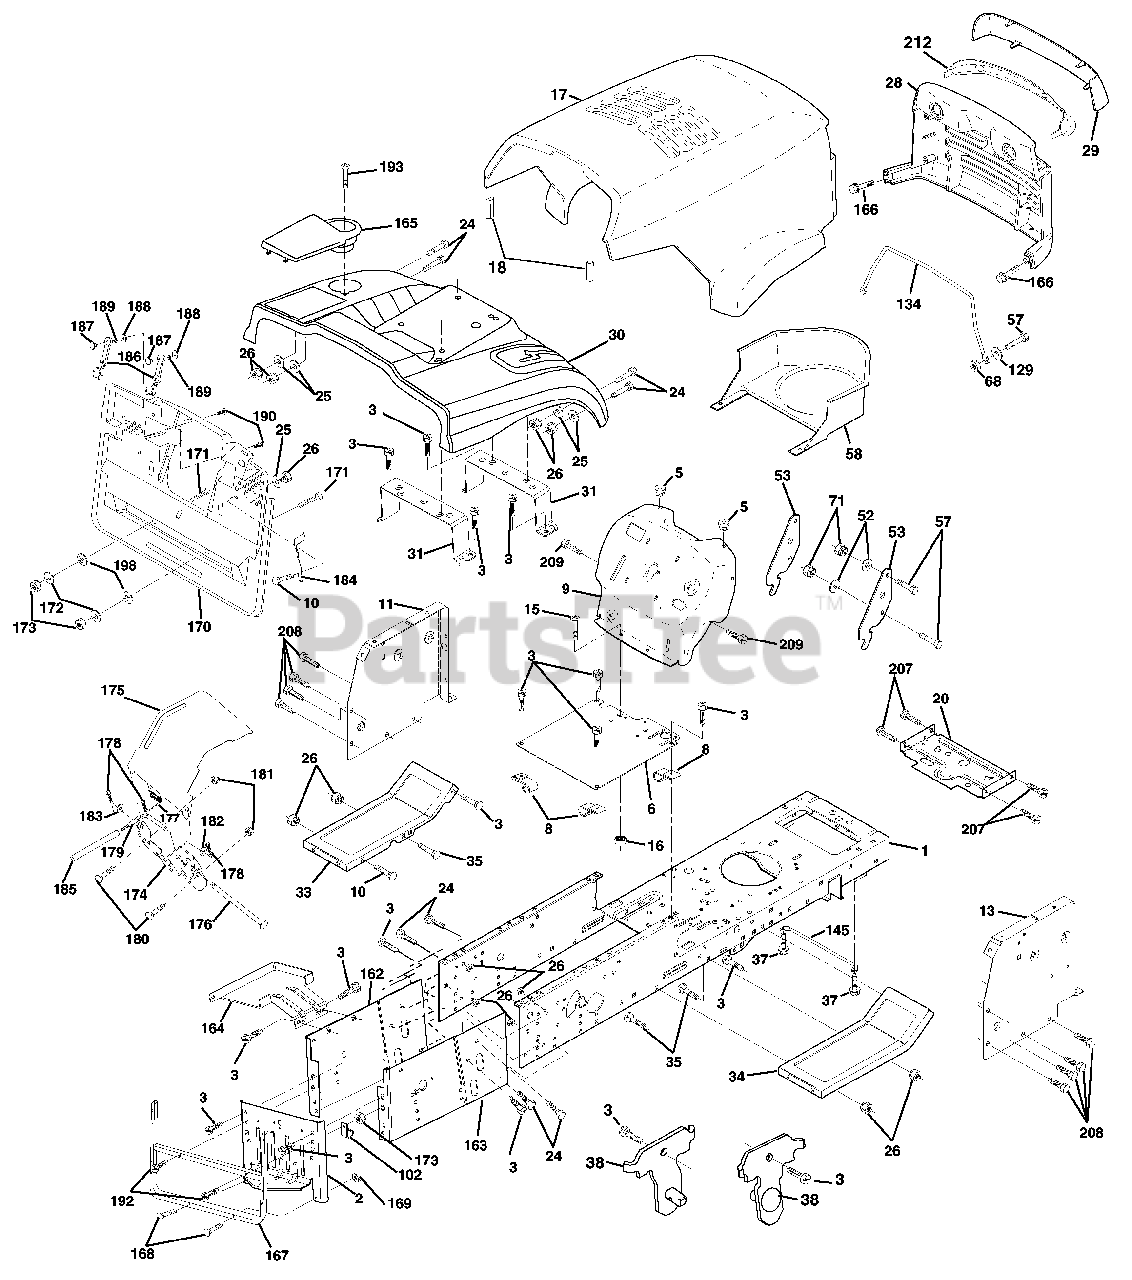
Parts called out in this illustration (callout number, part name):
1	Chassis Stamping
3	Screw 3/8-16 x 3/4
5	Bumper Hood/Dash
8	Clip Insulator 13/32 Mtg. Hole
10	Bolt, Carriage 3/8-16 x 3/4
11	Panel, Dash, L.H.
13	Panel, Asm. Dash R.H.
15	Screw, Machine, Truss Head 5/16-18 UNC x 3/4
16	Nut
17	Hood Assembly
18	Bumper Hood
20	Plate Mtg. Battery/Fuel Tank
25	Washer 13/32 x 13/16 x 12 Gauge
26	Nut
28	Grille PL
29	Lens, Grille
31	Bracket, Fender Support
33	Footrest, L.H.
34	Footrest, R.H.
37	Screw Thdrol 5/16-18 x 1/2 TYT
38	Bracket Asm Pivot Mower Rear
52	Washer 9/32 x 7/8 x 16 Ga.
53	Bracket Pick off LT/Pl Husq
57	Bolt, Fin Hex 1/4-20 UNC x .75
58	Duct Air Engine Pl/Lt
68	Nut Keps Hex 1/4-20 Unc
71	Nut Crownlock 1/4-20 Unc
102	Clip Line Fuel 13-13/32 Mtg. Hole
129	Washer 9/32 x 5/8 x 16 Ga.
134	Rod Support Hood Husq P/L
145	Rod Pivot Chassis/Hood
162	Bracket Exten Chassis Lh CRD
163	Bracket Exten Chassis Rh CRD
164	Support Battery CRD
165	Cover Battery CRD Lt
166	Screw Hwhd Hi-Lo #13-16 x 3/4
167	Support Asm. Backplate WLDMNT
168	Bolt, RDHD SHT NK 1/4-20 x 1-1/2
169	Nut, Lock 1/4 LGE FLG Gr. 5 Zinc
170	Cover, Backplate Plastic Black
171	Bolt Hex 3/8-16 x 2-1/2 Gr. 5
172	Washer 13/32 x 1-1/4 x 16 Ga.
173	Nut, Keps Hex 3/8-16 UNC
174	Bracket Switch FBI CRD
175	Guard Door Rear CRD
176	Pin Hinge Pivot
177	Spring Bagger Top LH Black
178	Pin Cotter 3/32 x 3/4 Cad Zinc
179	Rod Pivot FBI CRD
180	Bolt Hex HD 5/16-18 UNC x 1
181	Nut Crownlock 5/16-18
182	Washer .385 x .625 x 11 Ga.
183	Washer 13/32 x 13/16 x 16 Ga.
184	Bracket Actuator Bagger CRD
185	Tube Lever Switch FBI CRD
186	Latch Asm Mulch/Bagger
187	Nut Weld
188	Washer #10
189	Washer Lock #10
190	Washer Truss Head Phil 10-24 x 5/8
192	Screw Thdrol 3/8-16 x 1-1/4
193	Screw Truss 1/4-20 x 3/4 Tap/R
207	Screw Thdrol 5/16-18 x 1/2
208	Screw Thdrol 3/8-16 x 1/2
209	Screw Hexwsh Thdr 3/8-16 x 3/4
212	Insert Lens Reflective
